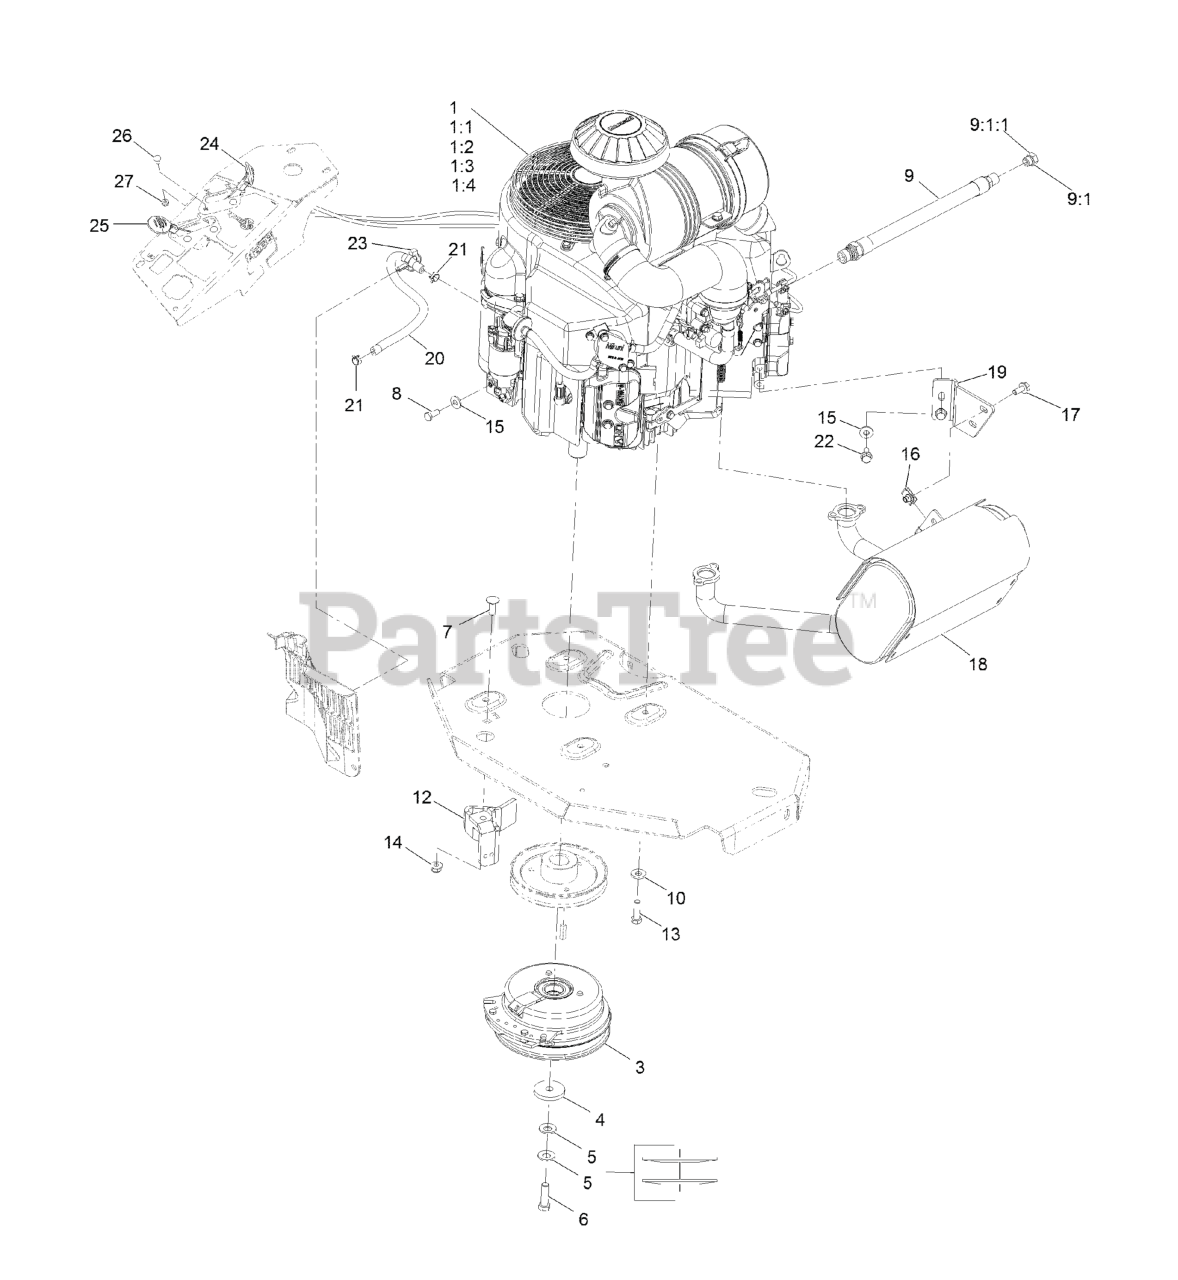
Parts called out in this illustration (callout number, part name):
1:1	Kawasaki 49065-2078 Engine Oil Filter
1:2	Kawasaki 49019-7001 Fuel Filter
1:3	Kawasaki 11013-7039 Safety Filter
1:4	Kawasaki 11013-7038 Air Filter
3	CLUTCH KIT
4	WASHER-CLUTCH
5	WASHER-SPRING
6	SCREW-HH 7/16-20 X 1 1/2 W/LOCTITE
7	SCREW-CARR
8	SCREW-HH
9	ENGINE OIL DRAIN HOSE ASM
9:1	PLUG-HH
9:1:1	O-RING
10	WASHER-BELLEVILLE
12	CLUTCH-ANCHOR
13	SCREW-HH
14	NUT-HF, NI
15	WASHER-SPRING
17	SCREW-HHF
18	MUFFLER
19	BRACKET-MUFFLER
20	HOSE-FUEL
21	CLAMP-HOSE
22	SCREW-HHF
23	CLAMP-HOSE
24	ASM, CHOKE CABLE
25	ASM,THROTTLE CABLE
26	BOLT-CARR
27	NUT-LOCK, NI
